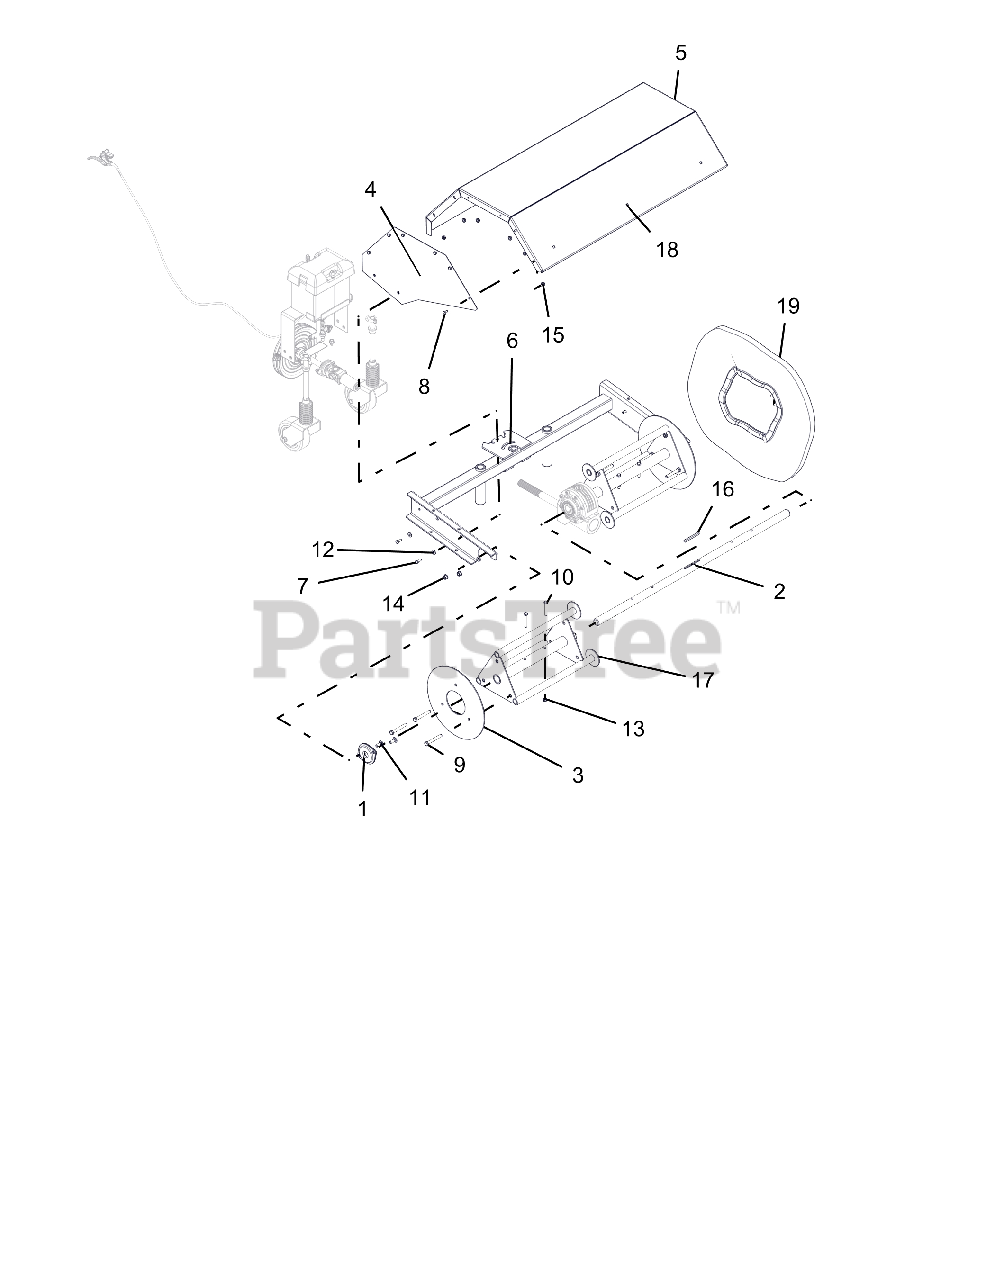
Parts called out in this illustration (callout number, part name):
1	BEARING, 2 BOLT FLANGE 1-1/8 ID
2	SHAFT, CENTER
3	PLATE, END - RETAINER
4	WLDMT, SIDE COVER RH
5	WLDMT, SIDE COVER LH
6	FRAME, POWER BROOM 36"
7	BLT-HEX .25-20X.75 GR5 YWZC
8	BLT-HEX .25-20X.50 GR5 YWZC
9	BLT-HEX .38-16X3.00 GR5 FTH YWZC
10	BLT-HEX .31-18X2.25 GR5 YWZC
11	BLT-RDHDSQNK .38-16X1.00 G5 YWZC
12	WSHR-FL-STL.312X.734X.065 YWZ
13	NUT-LK-CTR .31-18 YWZC
14	NUT, LK-TOP-FLG .38-16 YWZC
15	NUT, LK-TOP-FLG .25-20 YWZC
16	KEY-SQ .250X.250X3.00
17	BRUSH, DRIVE CORE - SERVICE KIT
18	COVER, TOP - 36" BRUSH W/DECALS
19	BRISTLE REPLACEMENT - SET OF 18
